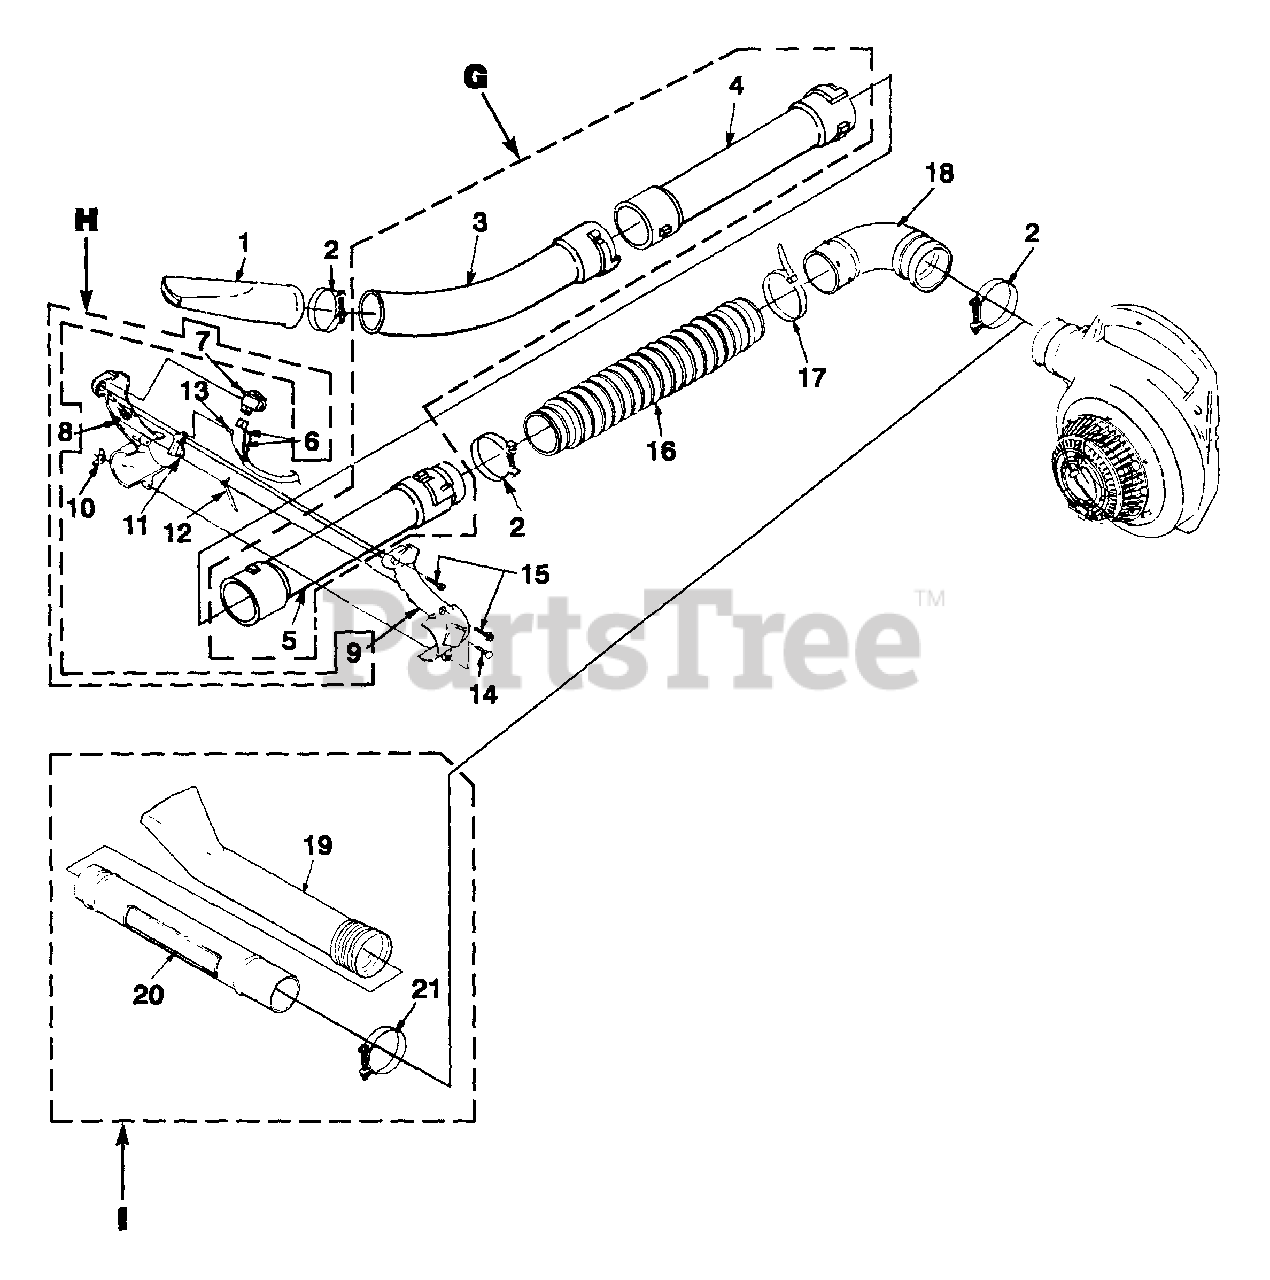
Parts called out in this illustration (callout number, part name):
1	Sweeper Nozzle
2	Clamp
3	Elbow
4	Straight Tube
5	Upper Tube
6	Electrical Lead w/Terminal
7	Switch
8	Control Handle (Right)
9	Control Handle (Left)
10	Wing Nut (10-24)
11	Trigger
12	Trigger Latch
13	Throttle Cable
14	Bolt-Rib Neck (Round Hd.) (10-24 x 7/8")
15	Screw-Thread Form. (10-24 x 3/4")
16	Bellows-Plastic
17	Cable Tie
18	Elbow-Curved
19	Sweeper Nozzle
20	Tube w/Decals
21	Clamp w/Fasteners
G	Blower Tube Kit
H	Handle & Switch Kit
I	Blower Tube Kit (PHB's)
